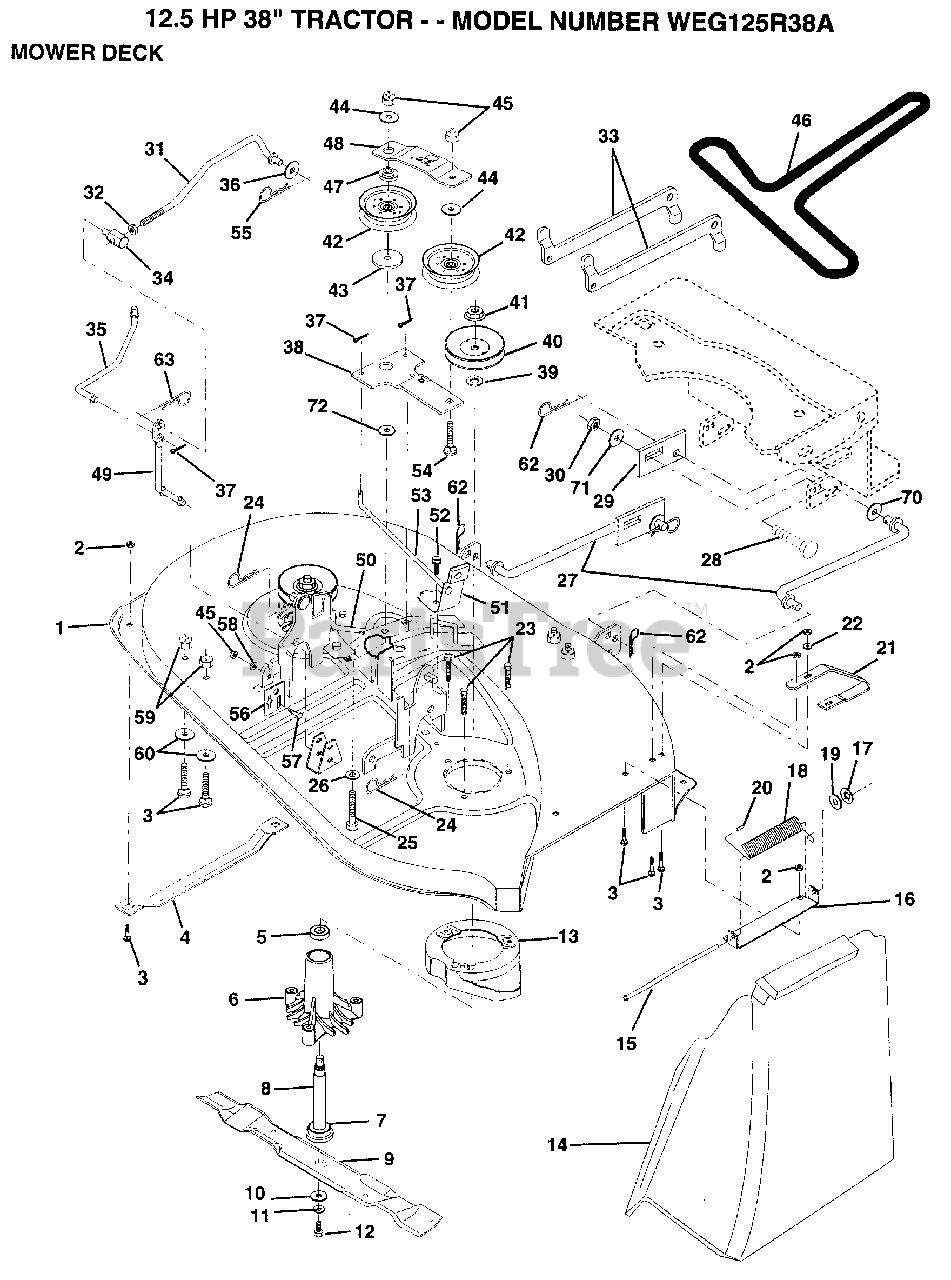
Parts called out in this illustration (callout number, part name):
1	MOWER.WELD.LR.38
2	NUT
3	BOLT
4	RUNNER-LH M
5	BEARING
6	HSG ASM MANDREL
7	BEARING.BALL
9	"BLADE.38""V.MULCH"
10	WASHER.HARD.BLADE
12	BLADE BOLT
13	STRIPPER, MOWER, VENTED
14	DEFLECTOR-SHLD T
15	ROD-HINGE T
16	BRKT DEFLECTOR
17	NUT PUSH M
18	SPRING TORSION
19	WASHER
20	CAP-SLEEVE LT
21	RUNNER RH
22	WASHER M
23	BOLT.5/16-18X1.25
25	BOLT
26	WASHER GT
27	"LINK LIFT 38"""
29	PLATE SLIDE LINK
30	NUT
31	ROD.CLUTCH.PRIM
32	NUT
33	SUSP ARM REAR
34	TRUNNION
35	CLUTCH ROD SEC
36	WASHER
38	IDLER ARM ASSY
39	WASHER
42	PULLEY IDLER
43	SPACER RETAINER
44	WASHER GT
45	NUT
46	V BELT
47	RETAINER SPACER
48	IDLER ARM STIFF
49	PIVOT ROD
50	BRAKE ROD LH
51	BRAKE ASM
52	SCREW
53	BRAKE ROD RH
54	BOLT
55	SPRING.RETAINER
56	PLATE ADJ LINK LH
58	WASHER T
59	NUT
60	WASHER.34X.68X16
62	RETAINER.SPRING
63	RETAINER M
70	WASHER 1/2X1 1/4
71	WASHER PM
72	HARDENED WASHER
